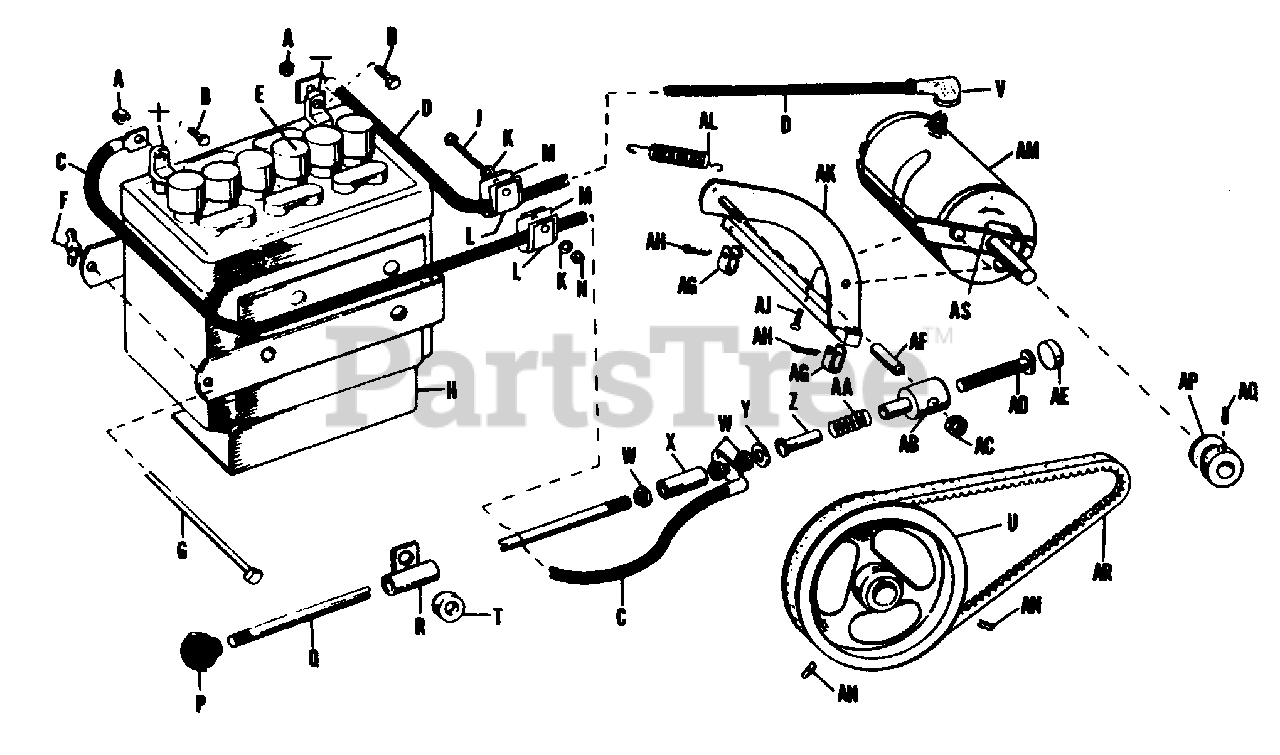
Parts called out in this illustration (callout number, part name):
A	Hex Nut, Full. 1/4"-20 NC
B	Capscrew, Hex Hd., 1/4-20 x 5/8
D	Cable Assembly
E	Battery (Purchase from Bat.Mfg.
F	Wing Nut,Lock, 1/4"-20 NC
G	Machine Bolt 1/4"-20 NC x 6" lg
H	Bracket Assembly, Battery
J	Screw, Rd. Hd. Mach., #10-24 x 1 1/2" lg.
K	Washer, Plain, 3/16" Std.
L	Clip, Cable
M	Lining, Clip
N	Hex Nut, Lock, #10-24
P	Knob, Starter
Q	Rod, Starter
R	Guide Assembly, Rod
T	Set Collar
U	Pulley, Engine
V	Cover, Terminal
W	Hex Nut, Jam, 5/16"-18 NC
X	Insulator
Y	Washer, Plain, 5/16" Std.
AB	Body, Switch
AC	Nut, Hex, Full Lock, 5/16"-18
AD	Bolt, Contact
AE	Plug, Switch Body
AG	Strap, Motor Support
AH	Pin, Cotter
AJ	Socket Screw, 1/4"-20 NC x 3/4
AK	Lever Assembly, Belt Tension
AM	Motor, Starter, (see note)
AN	Screw, Hex. Socket Cup Point Set, 5/16"-18 NC x 1/2" lg.
AP	Pulley, Motor
AQ	Screw, Hex. Socket Cup Point Set, 1/4-20 NC x 5/16" lg.
AR	"V" Belt, Starter 24" lg. Cog type 2
AS	Belt Stop Assembly
